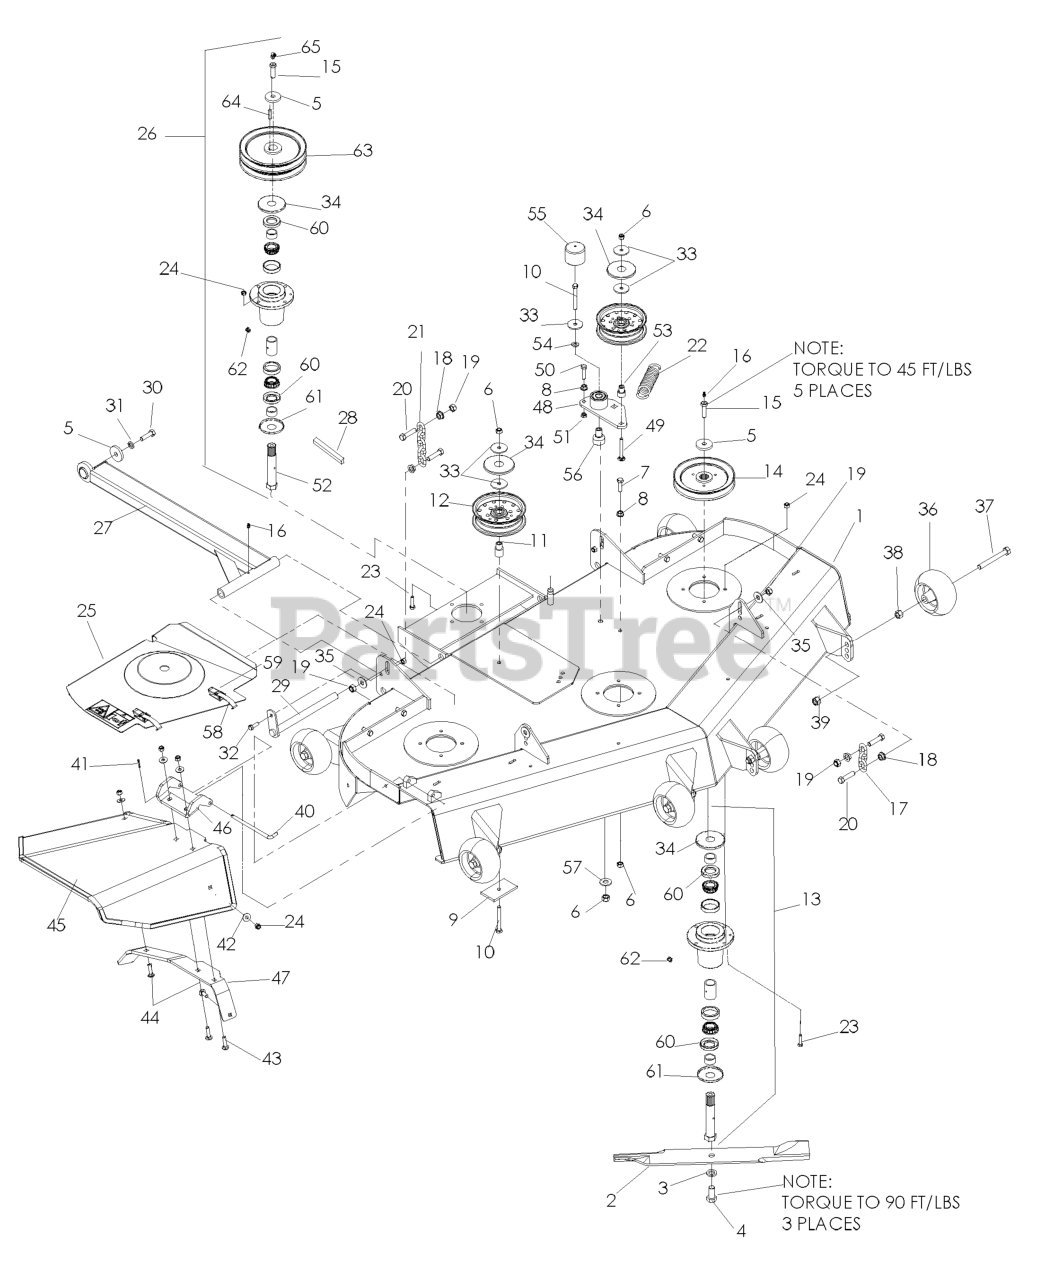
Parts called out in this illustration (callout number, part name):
1	DECK W/DECALS 61" TUNNEL HUS
2	BLADE OEM 21" (61" DECK)
3	LOCKWASHER 5/8
4	HCS 5/8F X 1 1/4
5	SPINDLE WASHER
6	NUT 3/8-16 NYLOC
7	HCS 3/8C X 1 1/4 GR5
8	NUT 3/8C WHIZ
9	SUPPORT PLATE
10	HCS 3/8C X 3
11	IDLER BUSHING
12	IDLER PULLEY
13	HOUSING ASM, 52/61
14	PULLEY, 61
15	HCS 7/16-20 GD 8 SPEC
16	ZERK
17	LIFT CHAIN - 3 LINK
18	NUT 7/16C WHIZ
19	7/16-14 HEX NUT W/NYL RING ZD
20	HCS 7/16 - 14 X 1 3/4
21	LIFT CHAIN
23	HCS 5/16C X 1 1/4
24	NUT 5/16 NYLOC
25	61 BELT SHIELD ASM - RH
26	BAM L44 JACKSHAFT ASM LOWER
27	STRUT WELDMT, L.H.
28	BELT, DECK
30	HCS 7/16F X 1 1/2
31	WASHER 7/16 LOCK
32	HCS 5/16C X 1
33	WASHER, 3/8 SPEC
34	TOP DUST CAP
35	WASHER 7/16 FLAT ZD
36	GAUGE WHEEL
37	HCS 1/2-13 X 4 GR 5 ZD
38	NUT HEX 1/2
39	NUT 1/2-13 HEX NYLOC ZD
40	PIN, CHUTE PIVOT
41	RP_COTTER PIN 1/8 X 3/4
42	WASHER 5/16 FLAT
43	RHSNB 5/16-18 X 1-1/2 GR 5 ZD
44	BOLT, CARRIAGE 5/16X1-1/4
45	CHUTE, RUBBER DISCHARGE 52/61"
46	PIVOT BRACKET - RUBBER CHUTE
47	BRACKET, REINF-CHUTE
48	ARM-IDLER W/BRG
49	RHSNB 3/8-16 X 2.75
50	HCS 3/8-16 X 1-1/2
51	NUT 3/8-16 HEX JAM
52	JACKSHAFT SPINDLE
53	BUSHING, IDLER
54	WASHER 3/8 SAE FLAT
55	CAP, VINYL
56	PIVOT, BEARING
57	WASHER 3/8 FLAT
58	DRAW LATCH
59	RIVET, BLIND, 5/32 DIA
60	SHAFT SEAL
61	BOTTOM DUST CAP
62	PLUG-VENTED
63	SHEAVE WSL
64	KEY 1/4 SQ X 1 1/8
